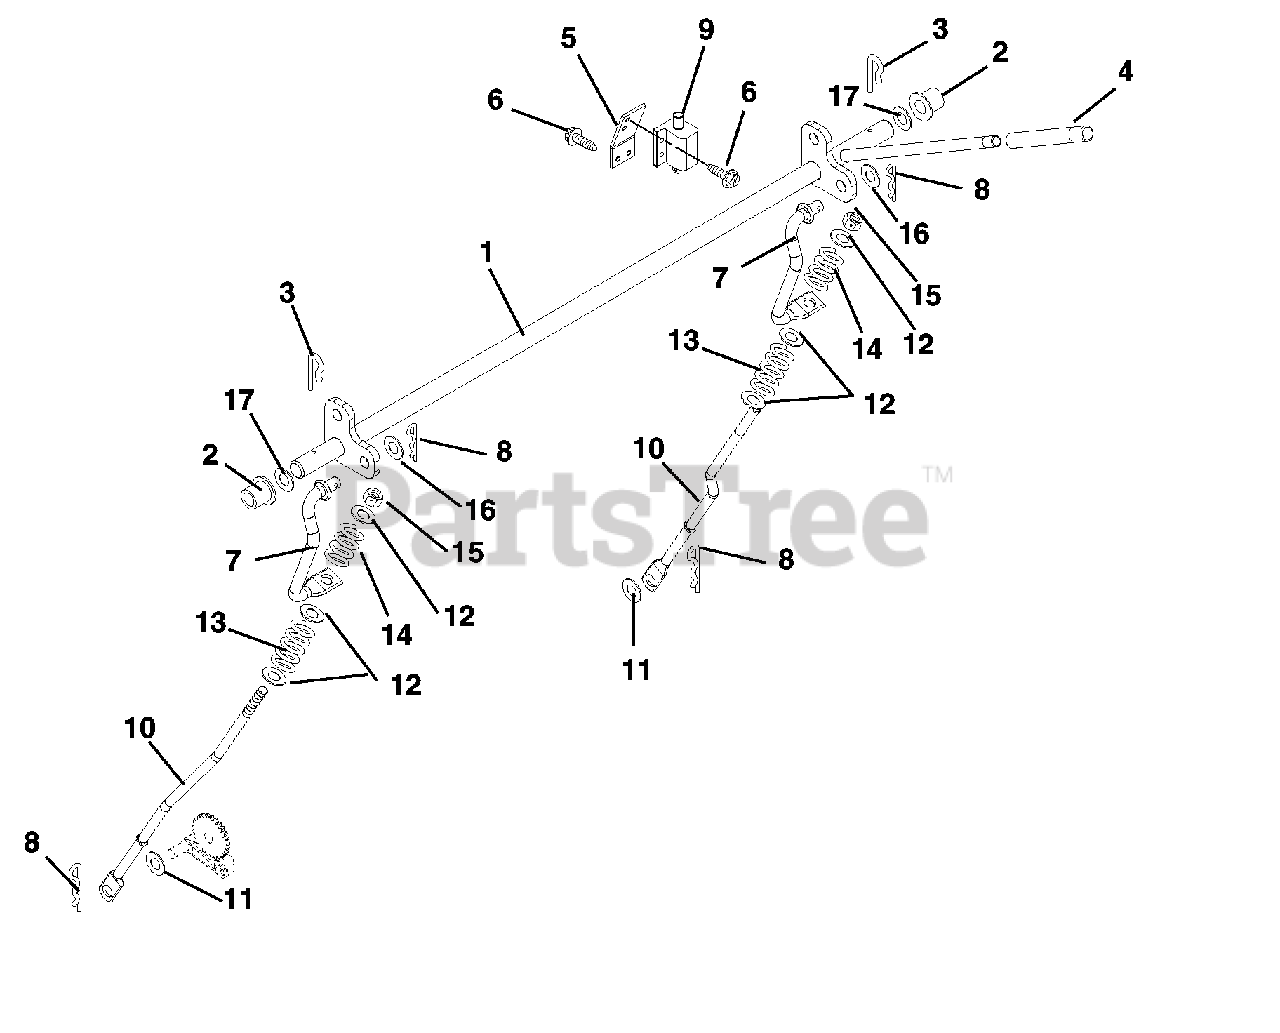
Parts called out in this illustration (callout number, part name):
1	WMT, ZOOM BRAKE ROD
2	BSHG-FLG .630X1.000X.625 NY
3	PIN, SPRING CLIP
4	GRIP,HAND CLUTCH LEVER
5	BKT-PARK BRAKE
6	@SCR-TAP 10-24X.50 HWH TR YWZC
7	ROD-OVER CENTER
8	PIN-HAIR, ENDRIES #25 YWZC
9	SWITCH, INTERLOCK NC
10	ROD-PARK BRAKE EZT
11	WSHR-FL-STL .406X1.00X.188 YWZ
12	@WSHR-FL-STL.344X.688X.065YWZC
13	SG-COMP .045X.50X1.187
14	SG-COMP .063X.53X1.187
15	@NUT-LK-NYL .312-18 YWZC
16	@WSHR-FL-STL.406X.812X.065 YWZ
17	WSHR-FL-STL .627X.990X.032
